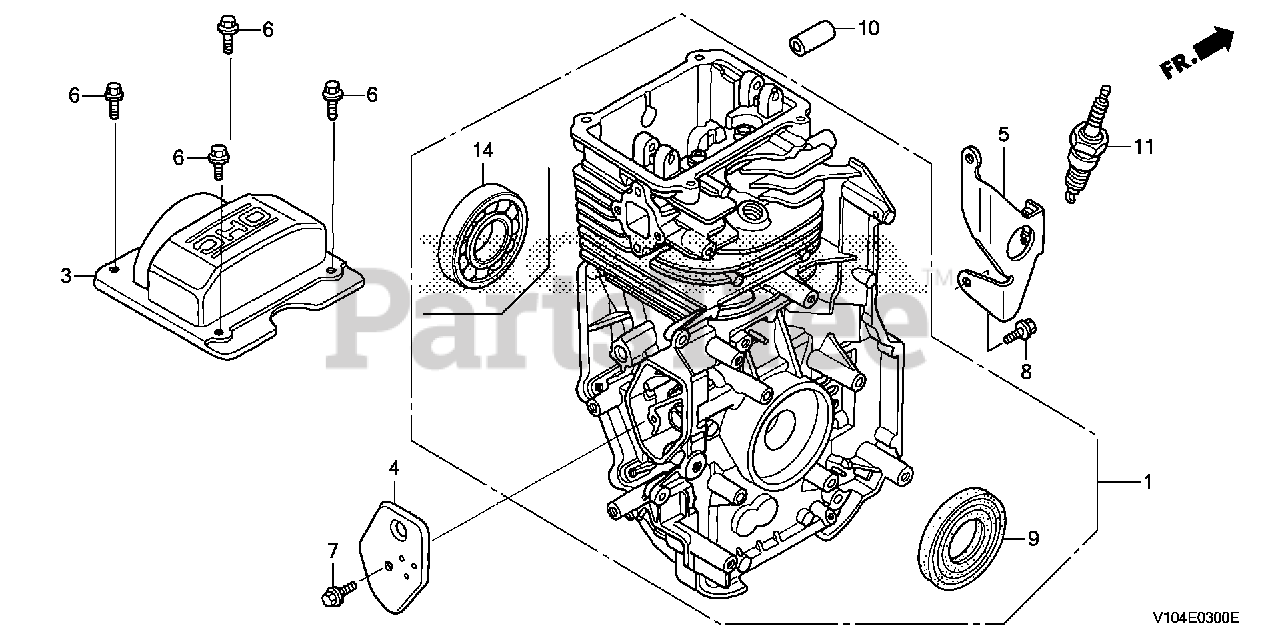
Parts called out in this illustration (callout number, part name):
1	CYLINDER ASSY.
1	CYLINDER ASSY
3	COVER, CYLINDER HEAD
4	COVER, BREATHER (Honda Code 5580006). (BREATHER VALVE ASSY.)
6	BOLT, FLANGE (6X12) (CT200)
7	BOLT, FLANGE (6X14)
9	OIL SEAL (25.4X62X6)
11	SPARK PLUG (BPR5ES) (NGK)
